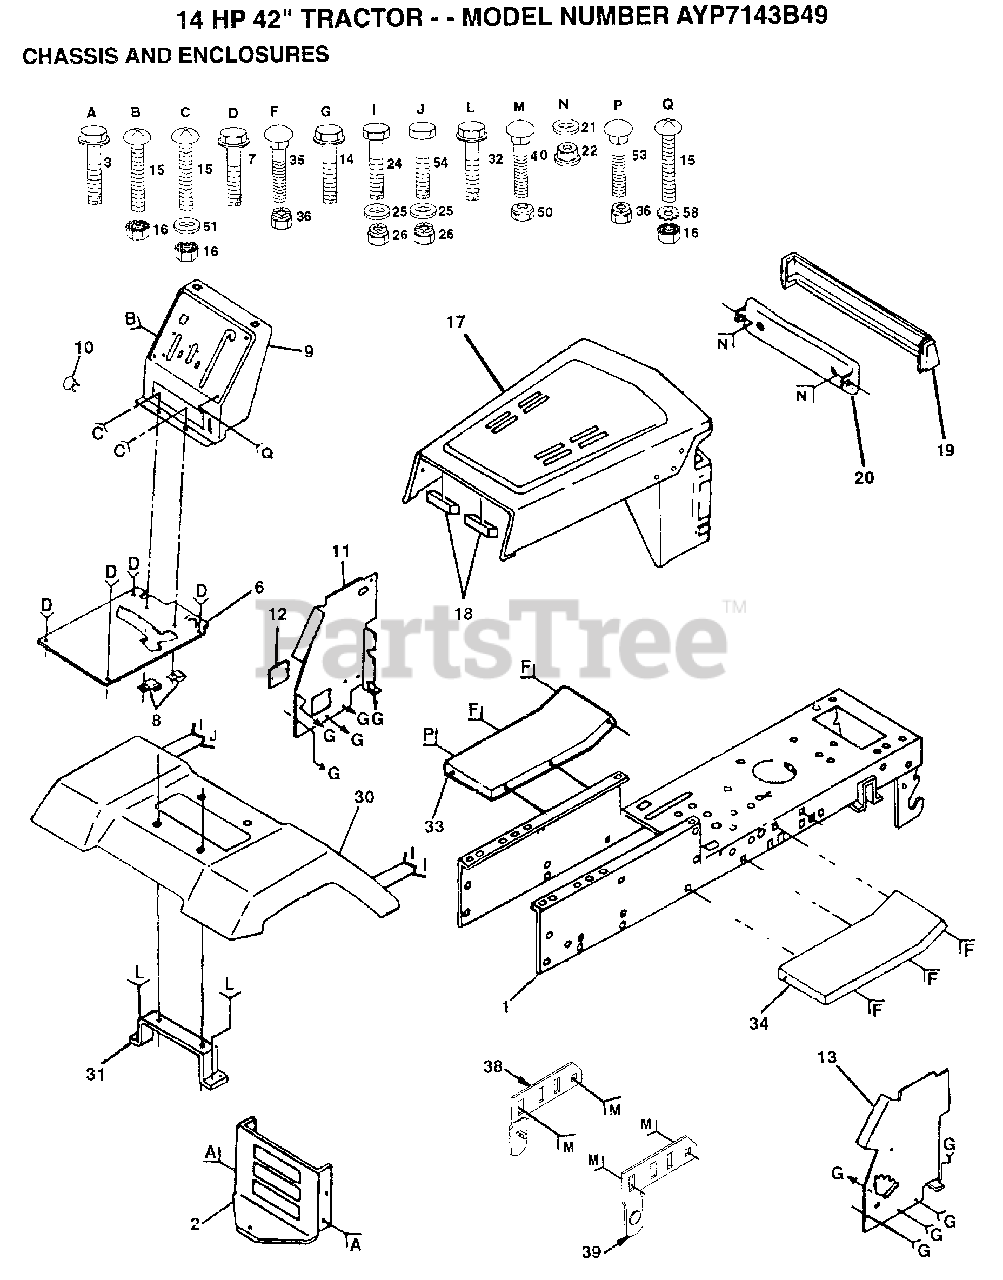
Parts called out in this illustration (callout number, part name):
3	SCREW
7	SCREW
8	CLIP T
9	DASH SILKSCRN 1
10	PLUG BUTTON T
11	PANEL DASH LH
12	COVER ACCESS
14	SCREW LT
15	SCREW
17	HOOD/GRILL ASM
21	WASHER PM
22	PAL NUT LT
25	WASHER
30	FENDER
31	BRKT FENDER
32	SCREW
33	FOOTREST LH
34	FOOTREST RH
35	BOLT
38	PIVOT BRKT LH
39	PIVOT BRKT RH
50	NUT
51	WASHER
58	LOCKWASHER
